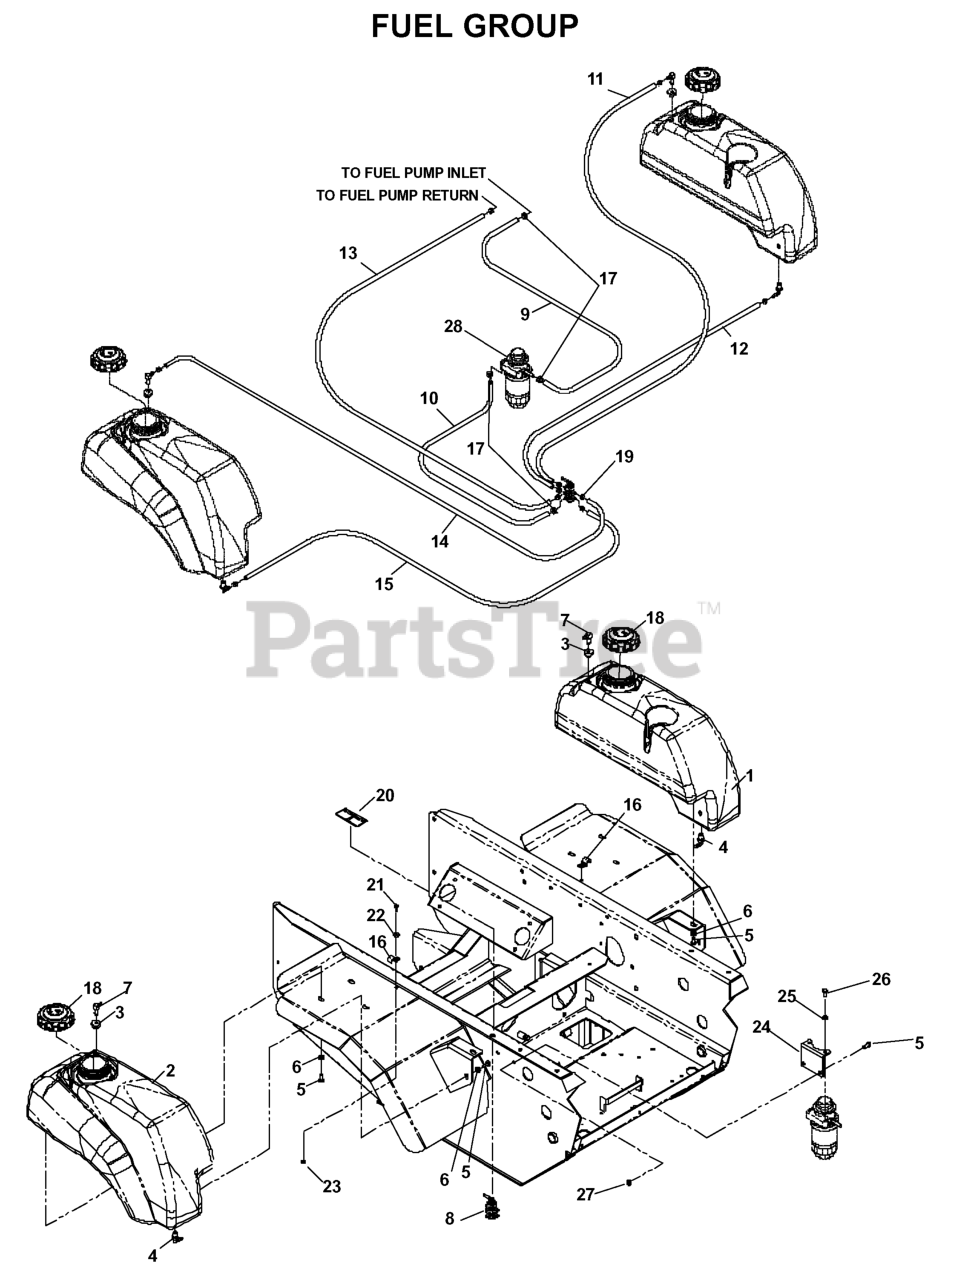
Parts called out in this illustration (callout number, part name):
1	FUEL TANK DIESEL LT
2	FUEL TANK DIESEL RT
3	RUBBER GROMMET
4	HOSE BARB 90 DEGREE
5	HCS 5/16C X 3/4
8	FUEL VALVE
9	FUEL LINE 38"
10	FUEL LINE 35"
11	FUEL LINE 79"
12	FUEL LINE 57"
13	FUEL LINE 54"
14	FUEL LINE 34"
15	FUEL LINE 13"
18	TANK CAP - DIESEL
19	HOSE CLAMP
20	FUEL VALVE DECAL
21	HCS 1/4C X 3/4 HCS
22	WASHER 1/4 FLAT
23	NUT.1/4-20.HEX.NYLOC.ZD
24	MOUNTING BRACKET
25	WASHER.LOCK.HVY.HLCL.SPR.5/16
27	NUT 5/16 NYLOC
28	FUEL FILTRATION SYSTEM
539106369	FUEL FILTRATION SYSTEM
